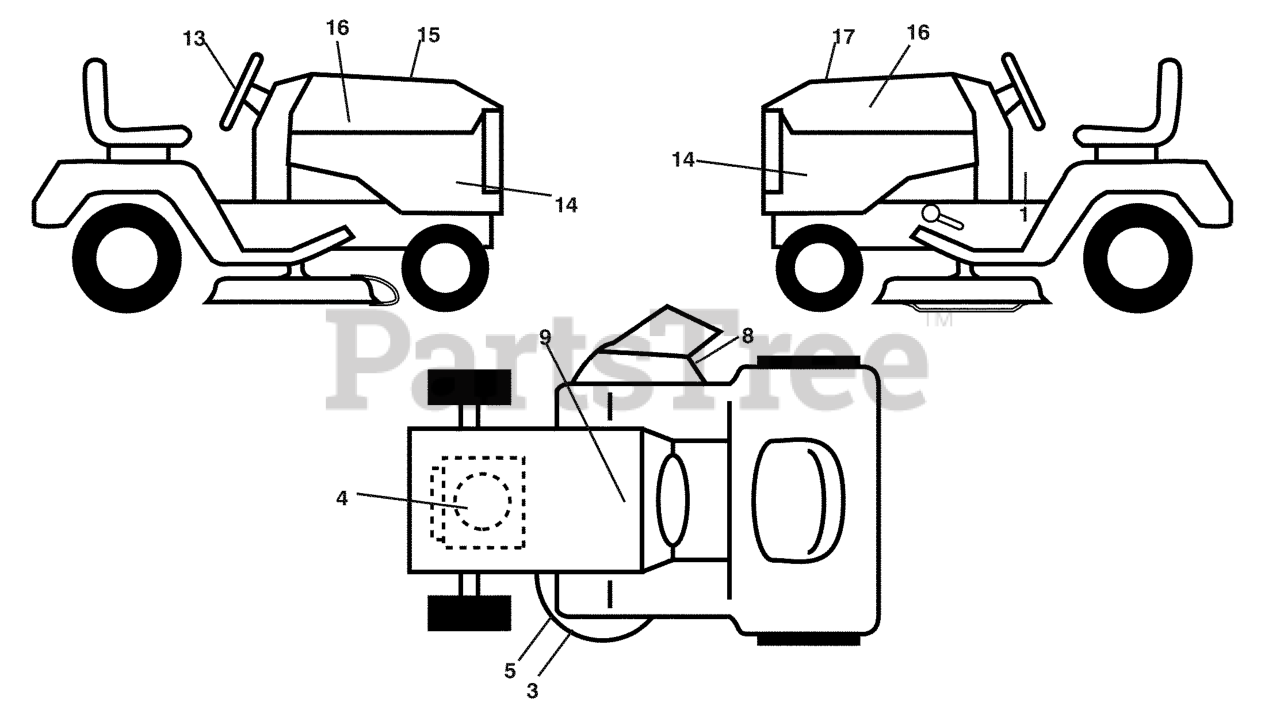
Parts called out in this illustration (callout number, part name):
1	DECAL.FENDER.WARNING.ENG
3	DECAL.WARN.KEEP.HAND.AWAY
4	DECAL, ENGINE, HP
5	DECAL CLUTCH/BRAKE
8	DECAL.MOWER.SCH.48/54
9	DECAL BTRY SYMBOLS
13	DECAL.WHEEL.STRG.LGN.H
14	DECAL PANEL
15	DECAL HOOD CUST. RESP.
16	DECAL.HOOD.NAMELOGO.HUSQ
17	Decal, Replacement
